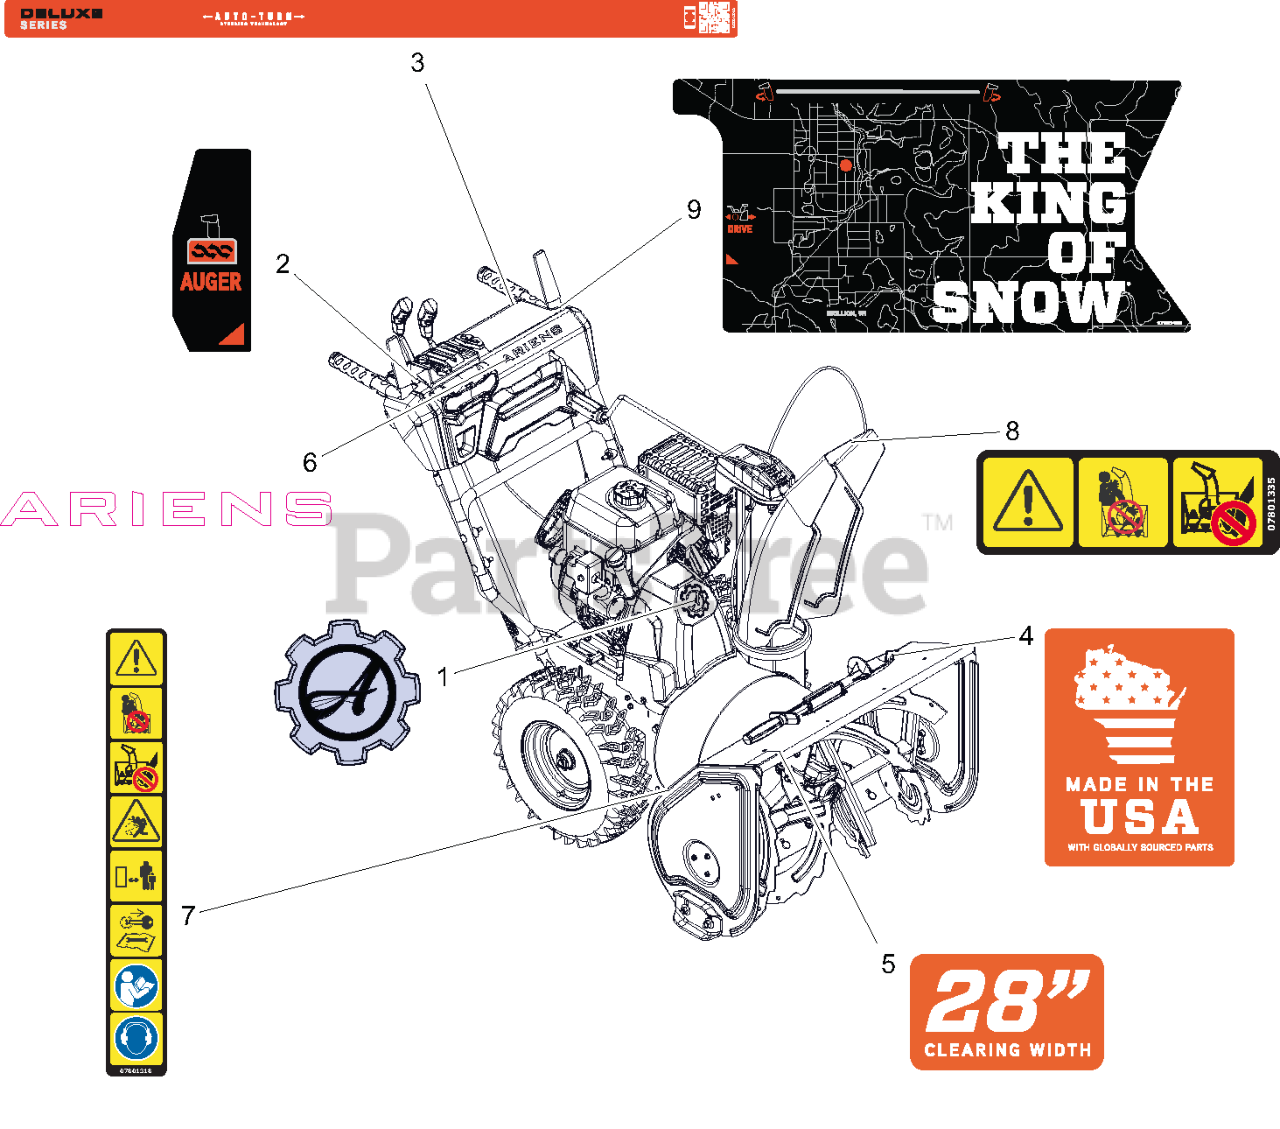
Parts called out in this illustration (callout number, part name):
1	DECAL- ARIENS GEAR BADGE
2	DECAL- CONTROL - AUGER
3	DECAL- DASH - DLX
4	DECAL- MADE IN USA
5	DECAL- CLEARING - 28
6	DECAL- ARIENS - 7.46"
7	DECAL- SAFETY - DANGER
8	DECAL- DANGER
9	DECAL-CONTROL-LG CHUTE ROTATE
